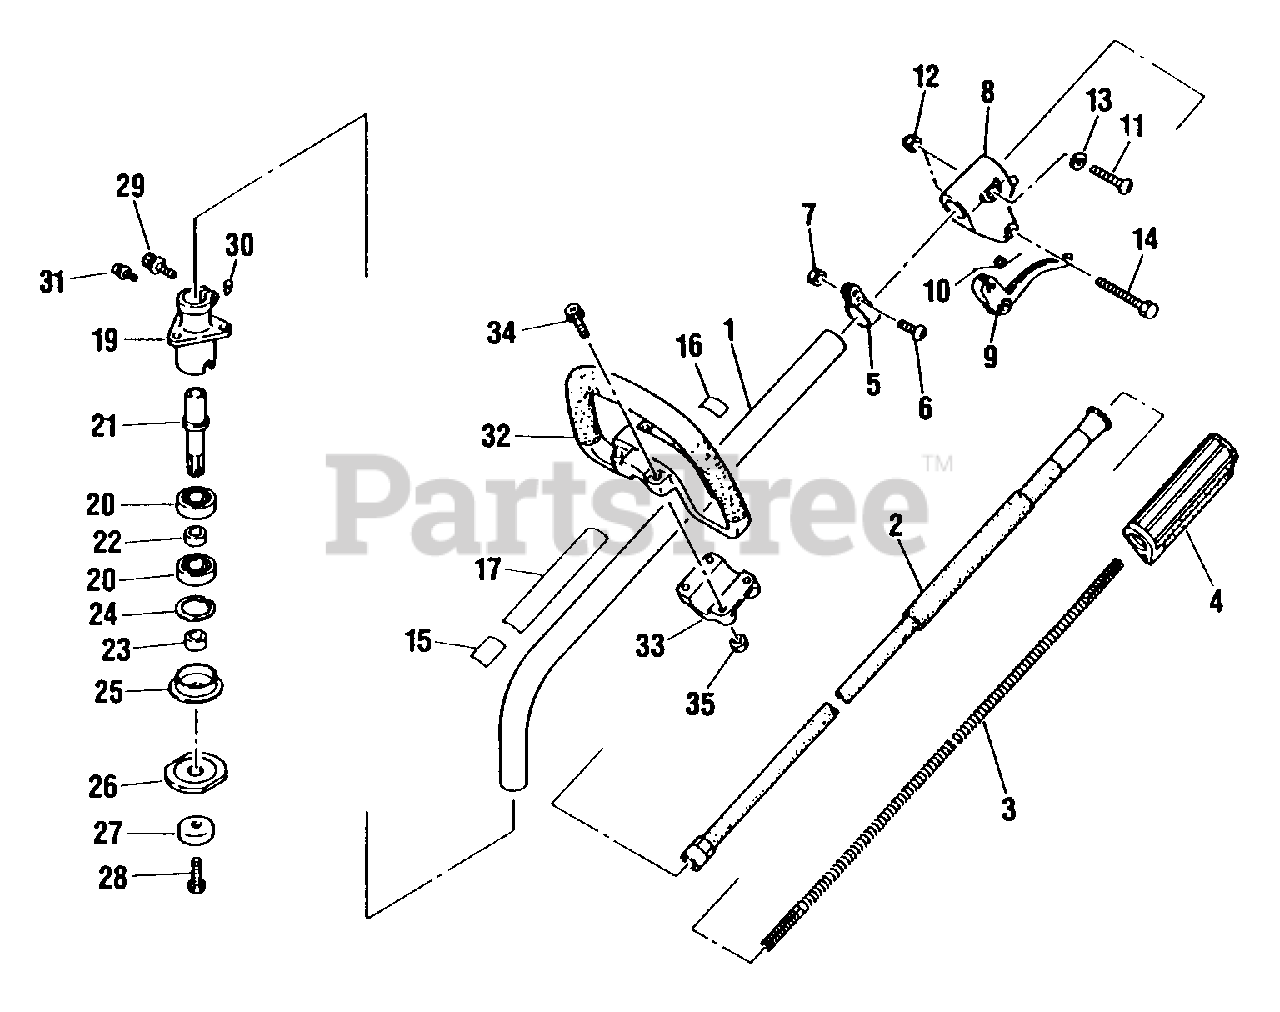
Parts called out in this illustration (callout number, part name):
1	PIPE - OUTER
2	LINER - FLEXIBLE
3	DRIVESHAFT - FLEXIBLE
4	GRIP
5	HANGER
6	SCREW - 5X12
8	BODY
9	TRIGGER, THROTTLE
10	SCREW - 5X20
11	SCREW - 5X20
13	WASHER - 5
14	BOLT - 5X25
15	LABEL - CAUTION
16	LABEL - ALIGNMENT
17	LABEL - MODEL
19	CASE, GEAR
20	BEARING, BALL - 6001DDU
21	SHAFT
22	SPACER - UPPER
23	SPACER - LOWER
24	RING, RETAINING - 28
25	HOLDER (A)
26	HOLDER (B)
27	GUARD
29	SCREW - 5X25
30	SHIM
31	SCREW - 5X10
33	CAP - LOWER
34	BOLT
